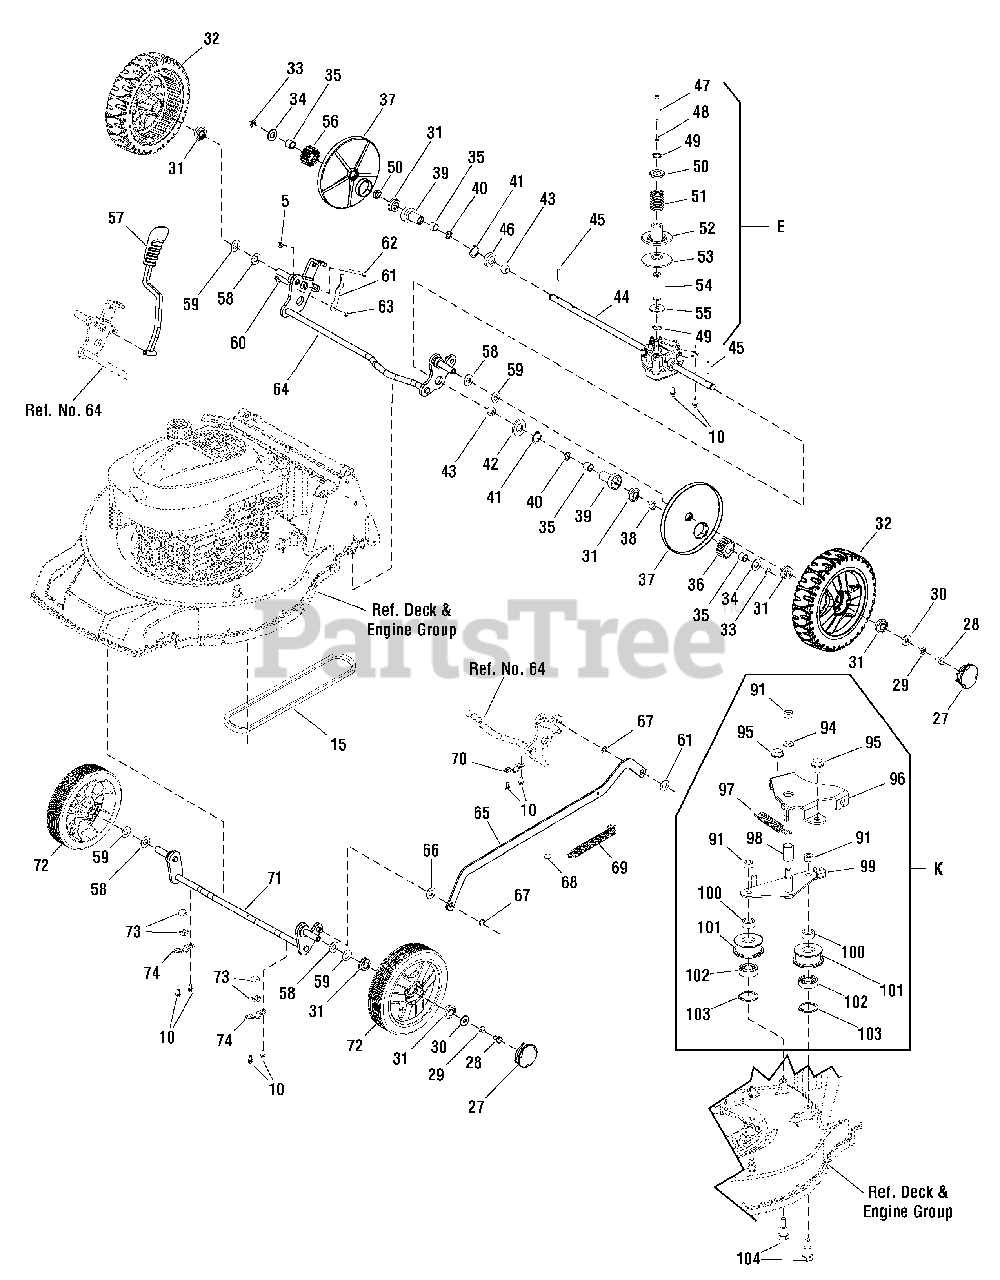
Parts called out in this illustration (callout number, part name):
5	NUT, Hex, Nylon Insert, Torque Type
10	SCREW, Hex Flange, Tapping
15	V-BELT, V10 x 795
15	V-BELT, V10 x 845
27	COVER, Wheel
28	BOLT, Hexangular, Full Thread
29	WASHER, Spring
30	WASHER, Flat, C Class
31	BEARING
32	WHEEL, Rear, Self-Propelled, 8"
32	WHEEL, Rear, Self-Propelled, 9"
33	CHECK RING
34	WASHER, Anti-Friction
35	OIL BEARING B
36	PINION, Left
37	SHIELD, Dust, Rear
38	SPACER, Main Axle
39	BEARING SHEATH
40	RING, Dustproof
41	RING, Elastic, For A-form Axle
42	WASHER, Left Bearing Bracket
43	BALL BEARING, Nylon
44	TRANSMISSION, 486
44	TRANSMISSION, 538
45	PIN, Sliding
46	SPACER, Transmission
47	CAPSCREW, Hexagon Socket Head
48	WASHER, Spring
49	RING, Elastic, For A-Form Axle
50	RING, Spring Shield
51	SPRING, Compression
52	Mobile Disc of Pulley
53	DISC, Lower Pulley
54	ADAPTOR
55	WASHER, Inner Hexagon
56	PINION, Right
57	LEVER, Height Adjust
58	WASHER, Wheel Axle
59	WASHER, Spring
60	BOLT, Hexangular, Full Thread
61	SPRING, Armature
62	BOLT, Hexangular
63	NUT, Hex, Nylon Insert, Torque Type
64	AXLE, Rear
65	CONNECTING ROD
66	MAT, Nylon
67	CHECK RING
68	CHECK CAP
69	SPRING, Connecting Rod
70	BRACKET, Upper Ball Bearing
71	AXLE, Front
72	WHEEL, Front, 8"
73	BALL BEARING
74	BRACKET, Front Ball Bearing
91	NUT, Hex, Nylon Insert, Torque Type
94	WASHER
95	BOLT, Hex Flange, Tapping
96	PLATE, Tension
97	SPRING, Tension
98	SPACER, Nylon
99	PLATE, Double Pulley
100	SPACER, Pulley
101	PULLEY, Tensional
103	RING, Elastic, For A-Form Hole
104	BOLT, Pulley
E	SPEED VARIATOR ASSEMBLY
K	TENSIONAL MECHANISM ASSEMBLY
